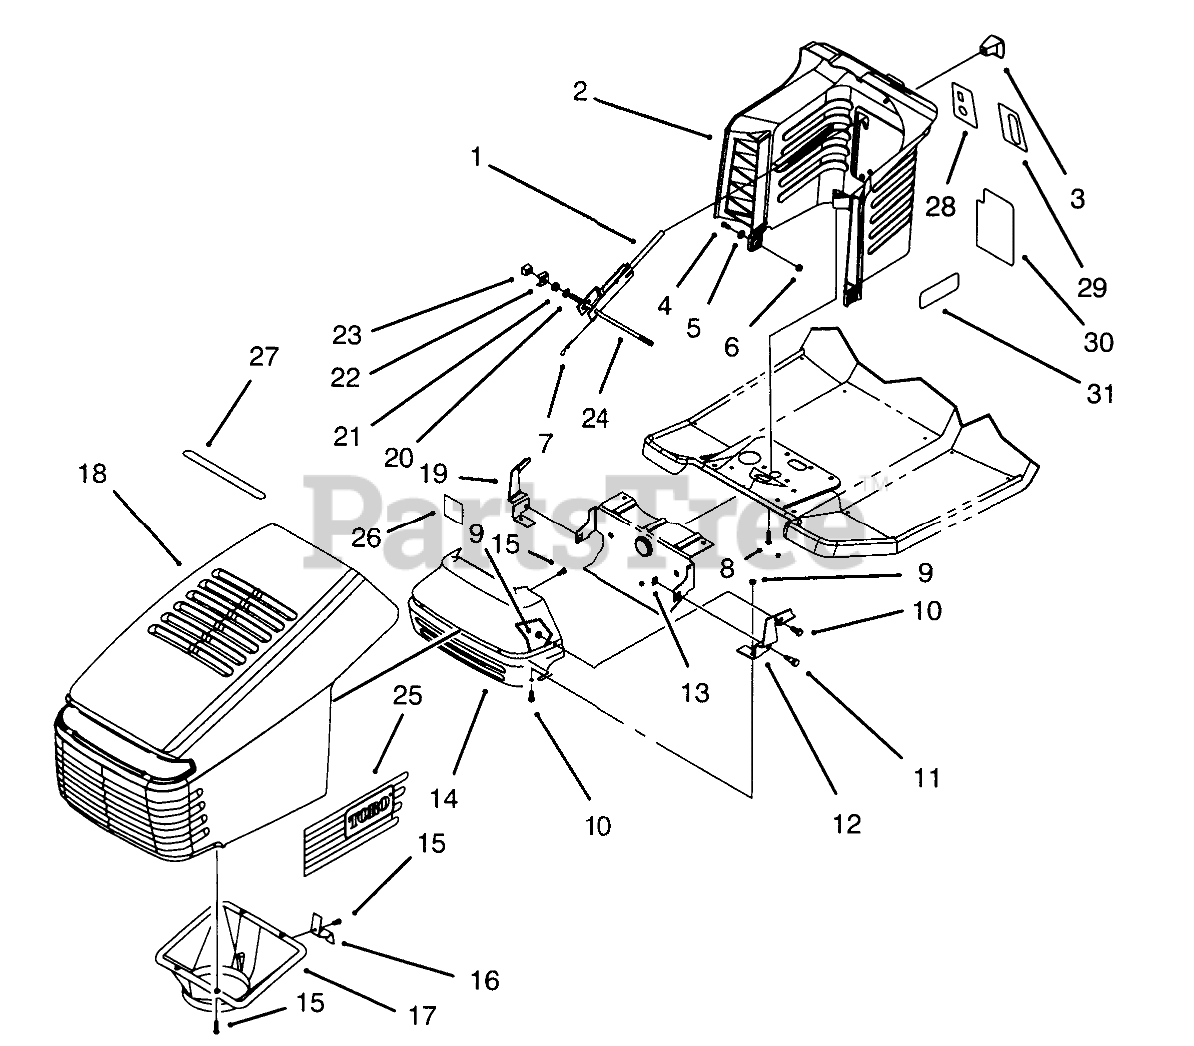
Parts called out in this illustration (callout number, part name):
1	Lever-Deck Engage
2	Tower-Steering
3	SHIFT KNOB
4	SCREW-HH
5	WASHER-PLAIN
6	NUT-LOCK, NI
7	PIN-COTTER
8	SCREW-HWH
9	NUT-LOCK, NI
10	SCREW-HH
11	BOLT-SHOULDER
12	Bracket-Hinge L.H.
13	NUT-RETAINER
14	Shield-Heat
15	SCREW-PLASTITE
16	HOOD LATCH
17	DUCT-AIR
18	HOOD ASM
19	Bracket-Hinge R.H.
20	WASHER-FLAT
21	NUT-FLANGE
22	ROD-CLAMP PIVOT
23	NUT-WEDGE
24	ROD-TOWER PIVOT
25	DECAL - HOOD RIGHT
26	TAPE-FOIL
27	DECAL-AIR DUCT
28	DECAL-IGNITION/LIGHTS
29	DECAL-THROTTLE/CHOKE
30	DECAL - DECK ENGAGE
31	DECAL - TOWER
